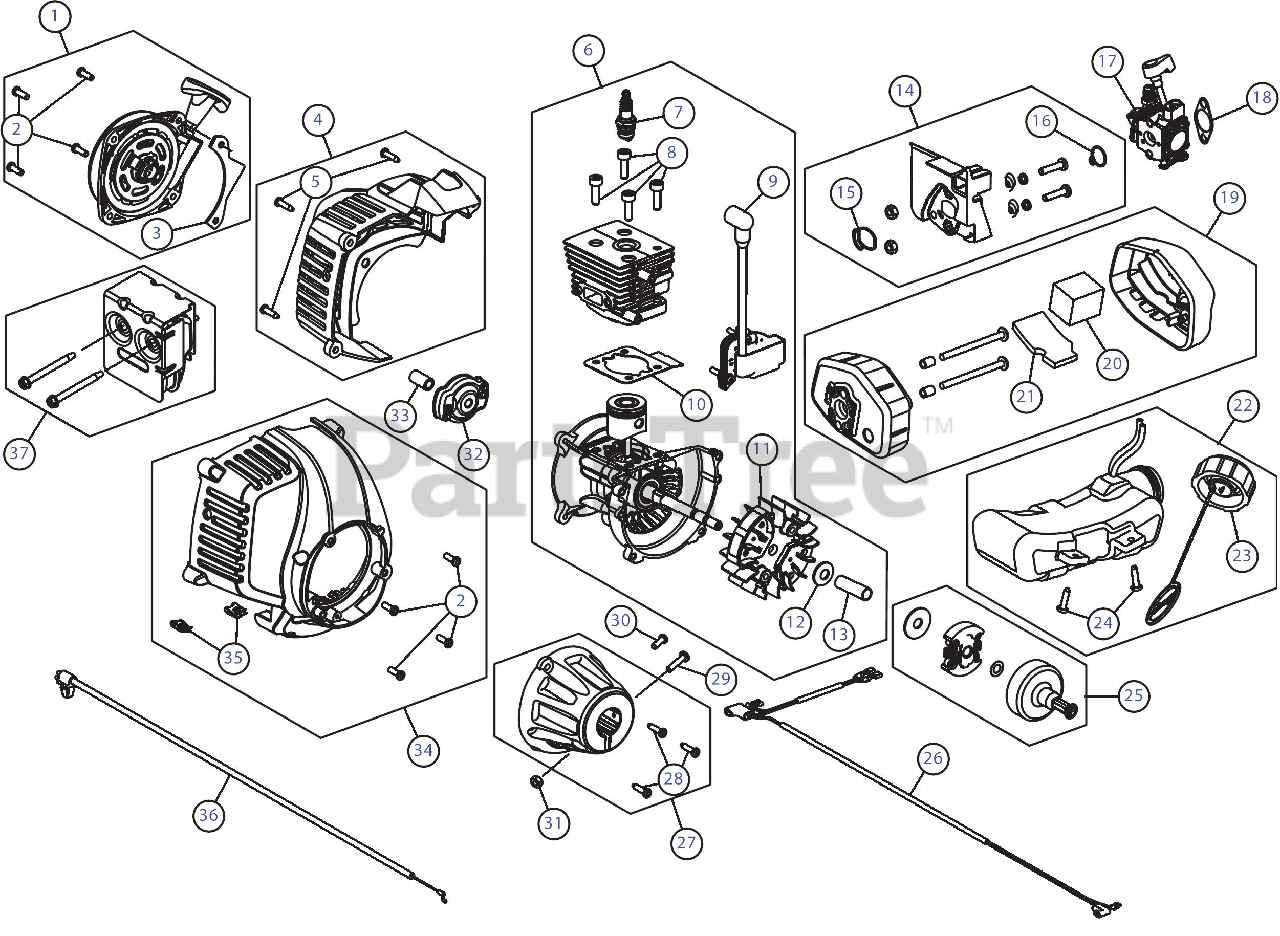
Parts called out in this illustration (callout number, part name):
1	Rear Cover Assembly
2	Starter Screw
3	Starter Assembly Guard
4	Rear Engine Cover Assembly
5	Cover Screw
6	Short Block Assembly
7	Spark Plug
8	Cylinder Bolt
9	Module Assembly
10	Cylinder Gasket
11	Flywheel Assembly
12	Washer
13	Spacer
14	Insulator Assembly
15	Insulator O-Ring
16	Carburetor O-Ring
17	Carburetor
18	Carburetor Gasket
19	Air Cleaner Assembly
20	Sound Filter
21	Media Filter
22	Fuel Tank Assembly
23	Fuel Tank Cap
24	Fuel Tank Screw
25	Clutch Assembly
26	Lead Wires
27	Clutch Cover Assembly
28	Cover Screw
29	Clamp Screw
30	Anti-Rotation Screw
31	Clamp Nut
32	Pawl Assembly
33	Adapter
34	Front Engine Cover Assembly
35	U-Shaped Nut
36	Throttle Cable
37	Muffler Assembly
